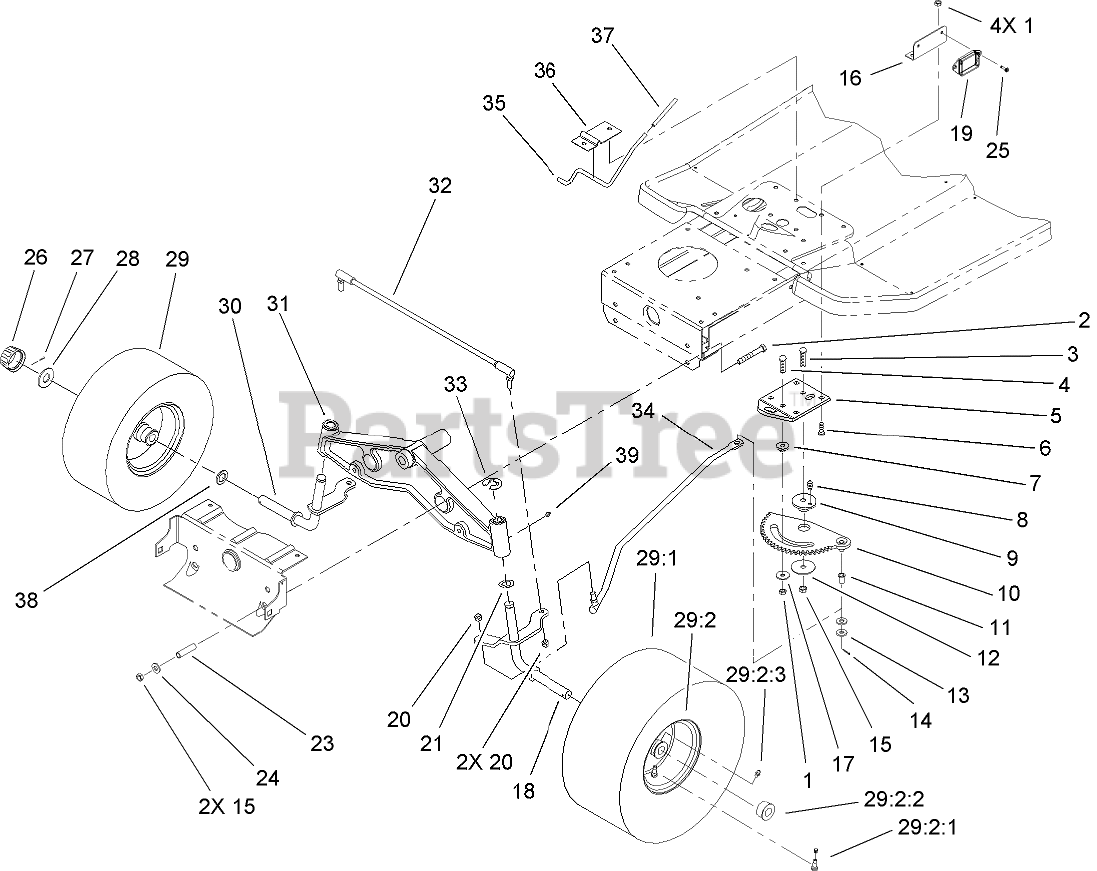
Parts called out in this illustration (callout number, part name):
1	NUT-LOCK, NI
2	SCREW-HH
3	SCREW-CARR
4	SCREW-CARR
5	BRACKET-RACK, STEERING
6	BOLT-CARR
7	SPACER-RACK, STEERING
8	FITTING-GREASE
9	BUSHING-ECCENTRIC
10	RACK-STEERING
11	BUSHING-FLANGED, NYLON
12	WASHER-BEARING
13	WASHER-FLAT
14	PIN-COTTER
15	NUT-LOCK, NI
16	BRACKET-MODULE
17	WASHER-PIVOT
18	SPINDLE-LH
19	MODULE-CLUTCH
20	NUT-HEX
21	WASHER-THRUST
23	SPACER
24	WASHER-FLAT
25	SCREW-HWH
26	CAP-HUB
27	PIN-COTTER
28	WASHER-PLAIN
29	FRONT WHEEL and TIRE ASM
29:2:1	STEM-VALVE
29:2:2	BEARING-WHEEL
29:2:3	FITTING-GREASE
30	RH SPINDLE ASM
31	AXLE-FRONT
32	TIE ROD ASM
33	E-RING
34	LINK-DRAG
35	ROD-BRAKE, PARKING
36	BRACKET-PARKING BRAKE
37	GRIP-BRAKE, PARKING
38	WASHER-THRUST
39	FITTING-GREASE
